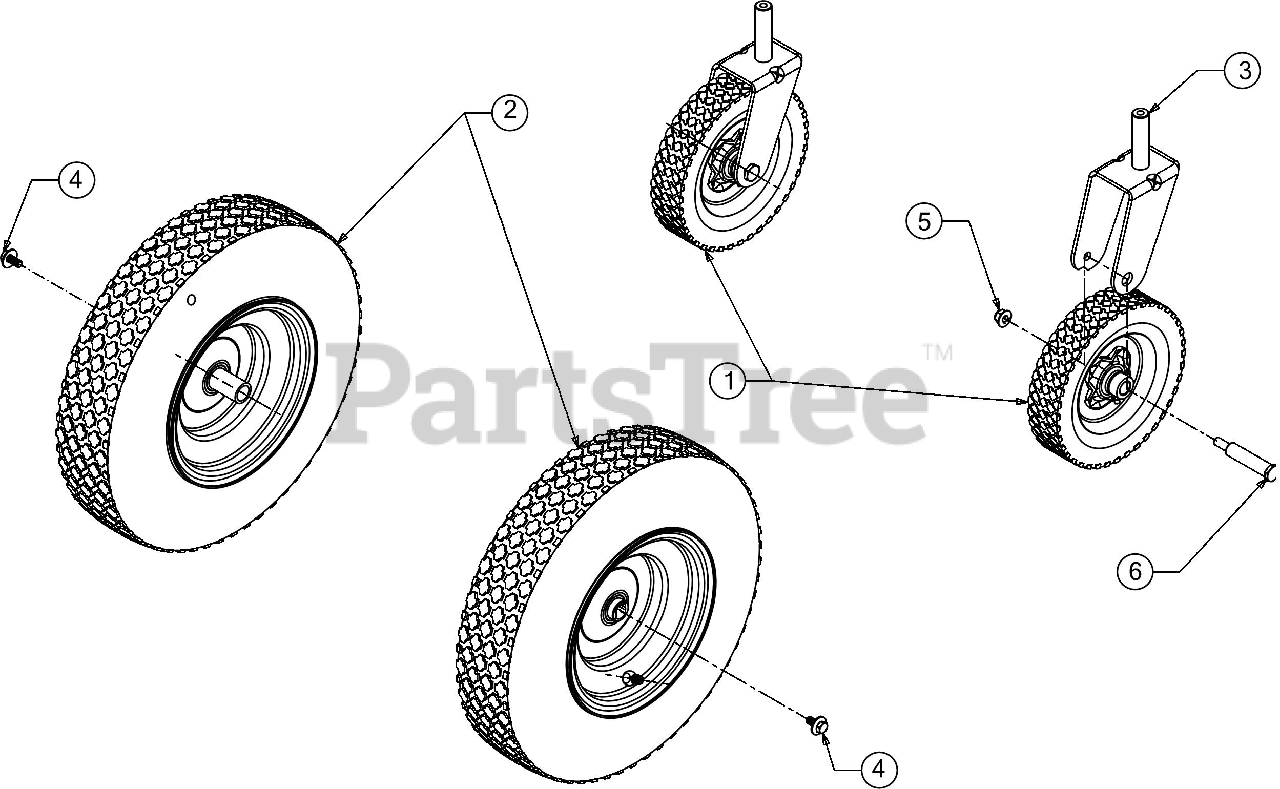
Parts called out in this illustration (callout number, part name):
1	FLANGE BUSHING
1	CASTER WHEEL
2	RIM ASSEMBLY (16 X 4 X 8) (BEIGE)
2	RIM ASSEMBLY (8.0X3.75) W/VALVE
2	TUBELESS VALVE
2	TIRE 4.80 X 8
3	CASTER WHEEL YOKE
4	SCREW 5/16-24 X .750 GR5
6	SHOULDER SCREW:.625 X 2.515 X 1.00
